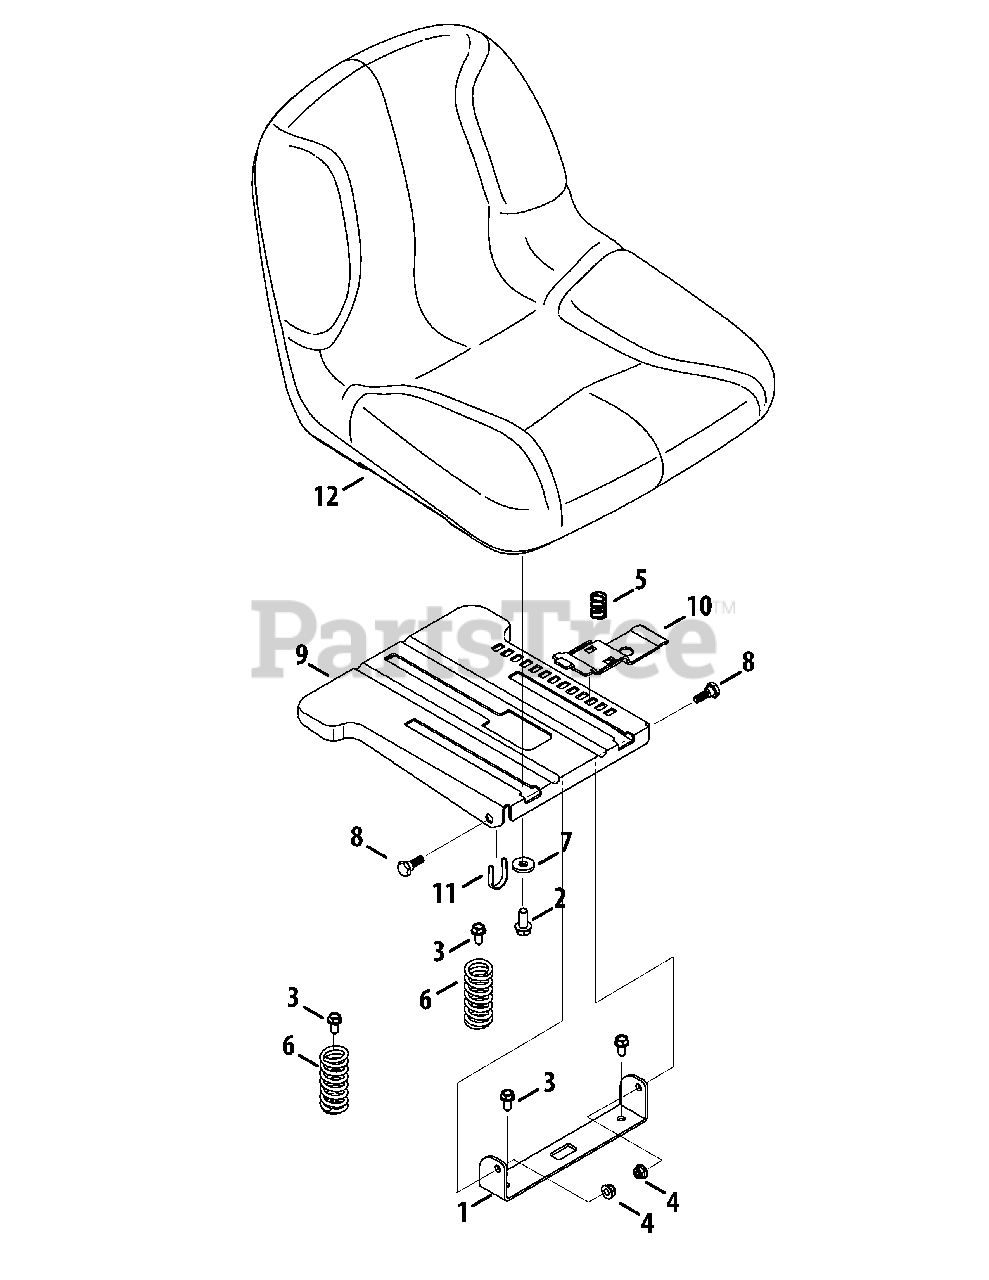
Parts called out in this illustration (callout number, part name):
1	Seat Bracket
2	Hex Flange Bolt, 3/8-16 x .875
3	Hex Washer Screw, 5/16-18 x .750
4	Flange Lock Nut, 5/16-18
5	Compression Spring, .68 x 1.065 x .055
6	Compression Spring, 1.50 x 3.90 x .200
7	Flat Washer, .385 x 1.00 x .135
8	Shoulder Screw, 5/16-18 x .437 x .268
9	Seat Mount Bracket
10	Seat Adjustment Lever
12	Seat
